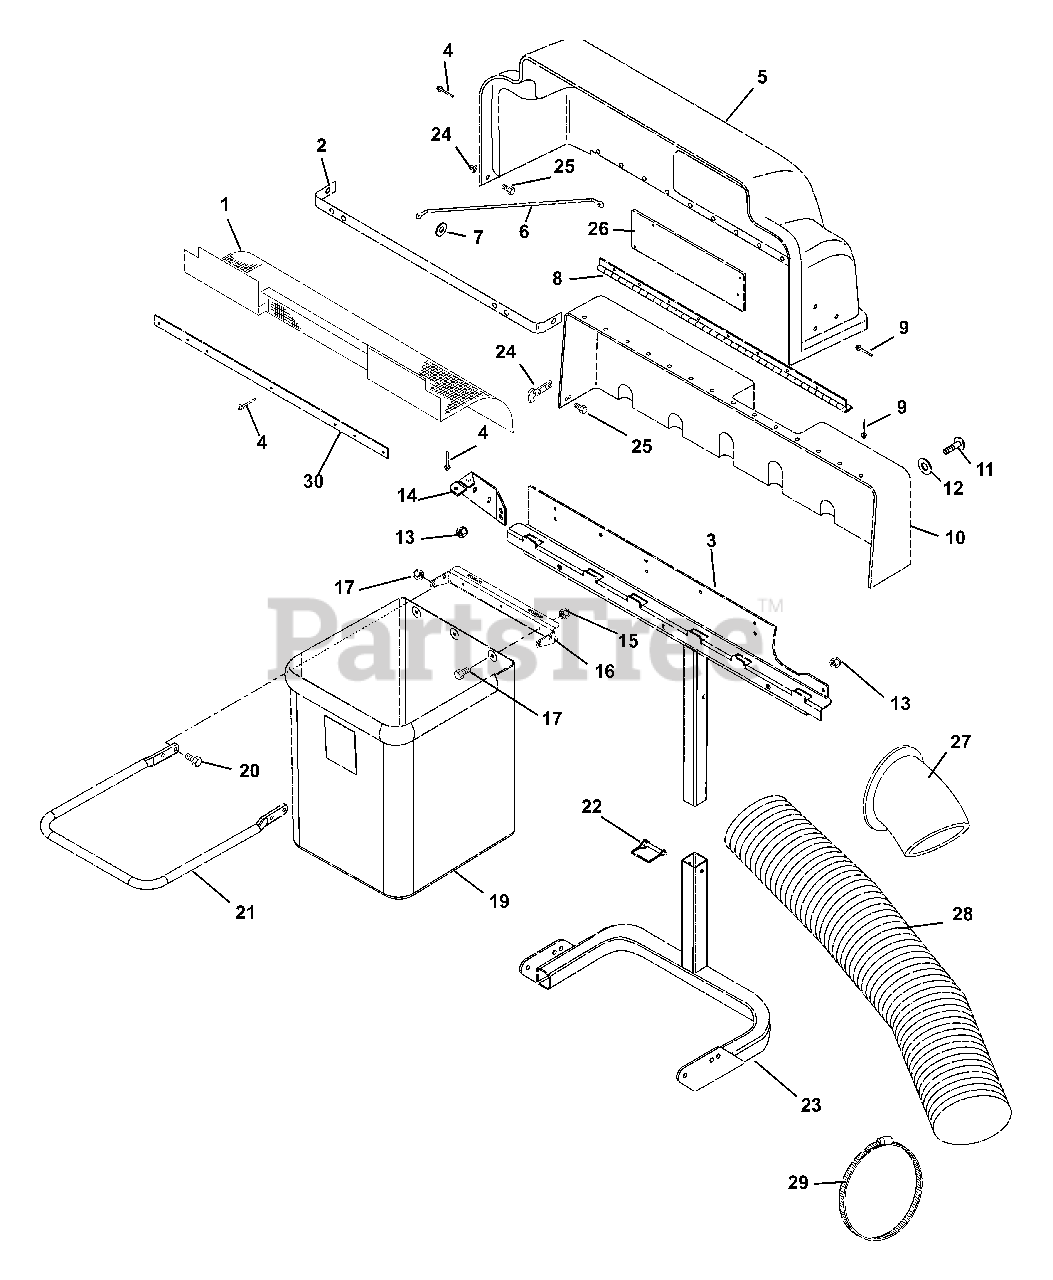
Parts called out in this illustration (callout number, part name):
2	Screen Mounting Bracket
3	Weldment-Bagger Frame
4	Rivet-Pop .187 x .527
4	(Gravely Part Number)
5	Hinged Cover with Decal
6	(Gravely Part Number)
7	Washer-Flat-Steel .194 x .492 x .047
9	Rivet-Pop .187 x .402
10	Stationary Cover
10	(Gravely Part Number)
11	Bolt-Hex .31-18 x 1.00 Grade 2
12	Washer-Flat-Steel .344 x .063
13	Nut- Locking-Nylon .312-18 Grade 2
14	(Gravely Part Number)
15	Nut-Locking-Center .25-20
16	Weldment, Hanger Frame
17	Bolt-Hex .25-20 x .50 Grade 5
18	Nut-Spin Lock-Flange .312-18
19	Bag-Mesh Assist Bagger
20	Bolt-Round Head Square Short Neck .31-18 x .75 Grade 5
21	Frame-Bag Support
22	Pin-.38 x 2.50 Square Lock
23	Weldment-Bumper Pivot
24	Latch, Rubber
25	Screw-Machine 10-24X.50 Hex Washer Head
27	Bagger Boot- Upper
27	(Gravely Part Number)
28	Hose 7 x 45
29	Clamp-Hose Worm 2.13/8.62X.56
29	(Gravely Part Number)
30	Guard, Screen
